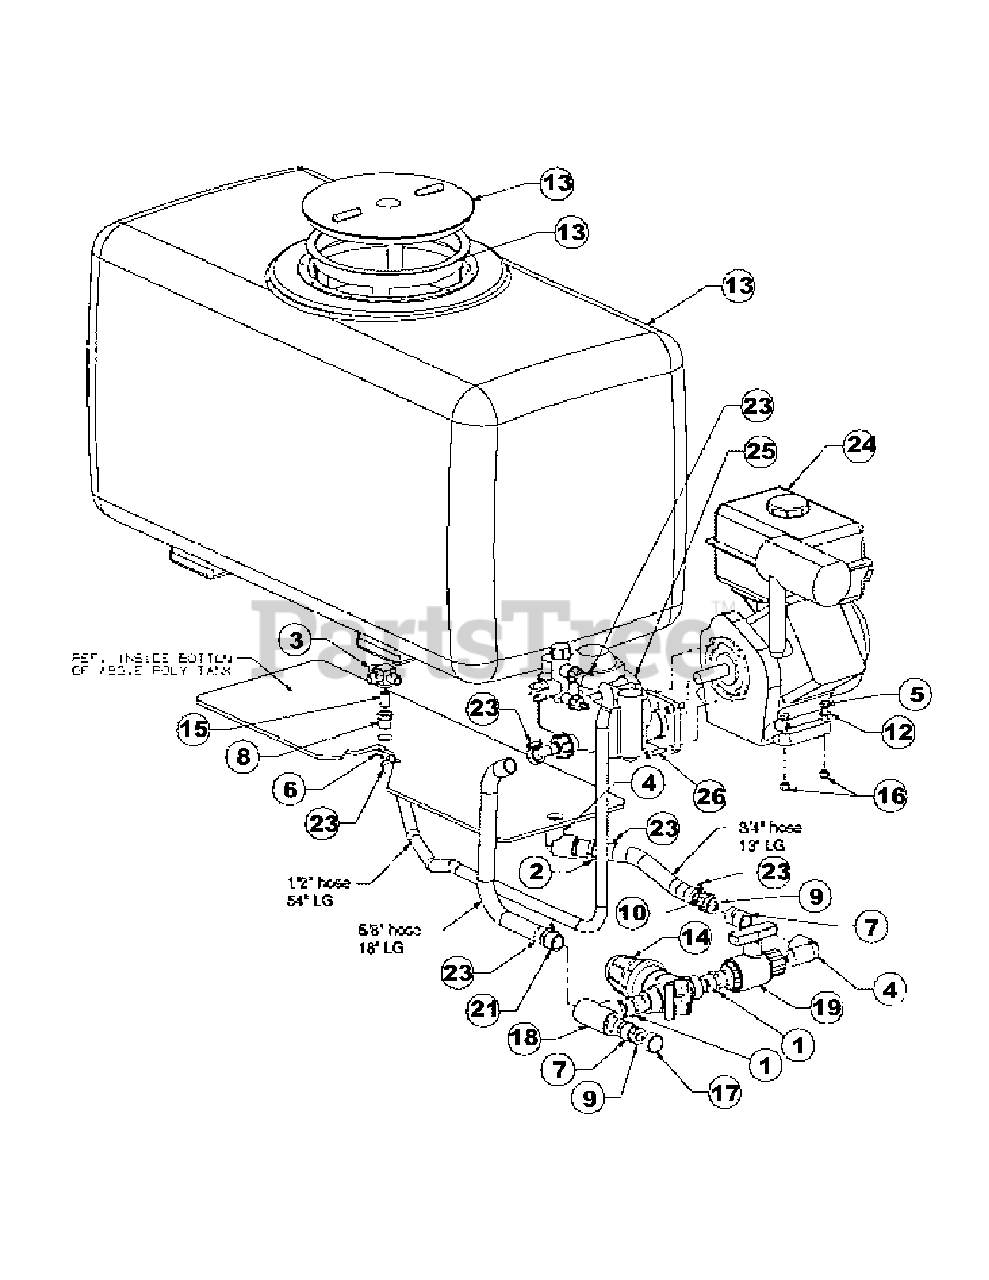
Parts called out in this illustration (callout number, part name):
1	Nipple, 3/4'' NPT
2	Adaptor, Male 3/4''
3	Jet Agitator
4	Street Elbow 3/4 NPT
5	Hex Cap Screw, 5/16-18 x 1-3/4
6	Hose Barb, 1/2 NPT, 1/2 Nylon
7	Adaptor, 3/4 NPT, 3/4 Hose Thread
8	Adaptor, 1/4(F) NPT 1/2 (M) NPT
9	Rubber Washer, Hose 3/4
10	Brass Repair Hose, Female 3/4
11	Hose, 1/2'' (800 PSI) in inches
12	Flat Washer, 5/16
13	50 Gallon Tank Includes:
13	Tank Lid 10''
13	Strainer Basket 10''
14	Strainer PVC Line 3/4''
15	Close Nipple, 1/4(M) NPT
16	Nylock Nut, 5/16-18
17	Brass Hose Cap, 3/4''
18	Tee, 3/4 NPT
19	Ball Valve
20	Hose, 5/8'' in inches
21	Hose Barb, 3/4 NPT x 5/8 Nylon
22	Hose, 3/4'' in inches
23	Hose Clamp, 1/2, 7/8
24	Engine, 4-HP Kawasaki Recoil Start
26	Socket Head Cap Screw, M-8-1.25 x 25mm
